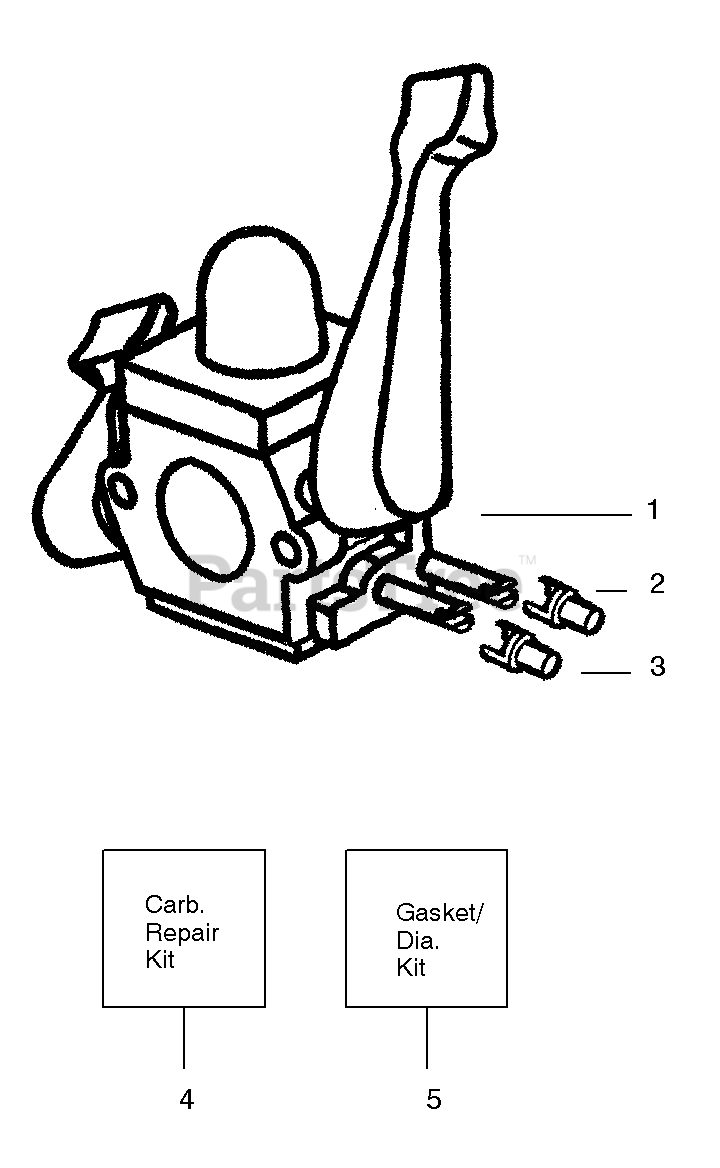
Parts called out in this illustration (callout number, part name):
1	Assy-Carb. Zama (C1Q-W11)
2	Cap-Limiter (high) brown
3	Cap-Limiter (low) tan
4	Kit-Carb. Repair
5	Kit-Dia. (GND-34)
